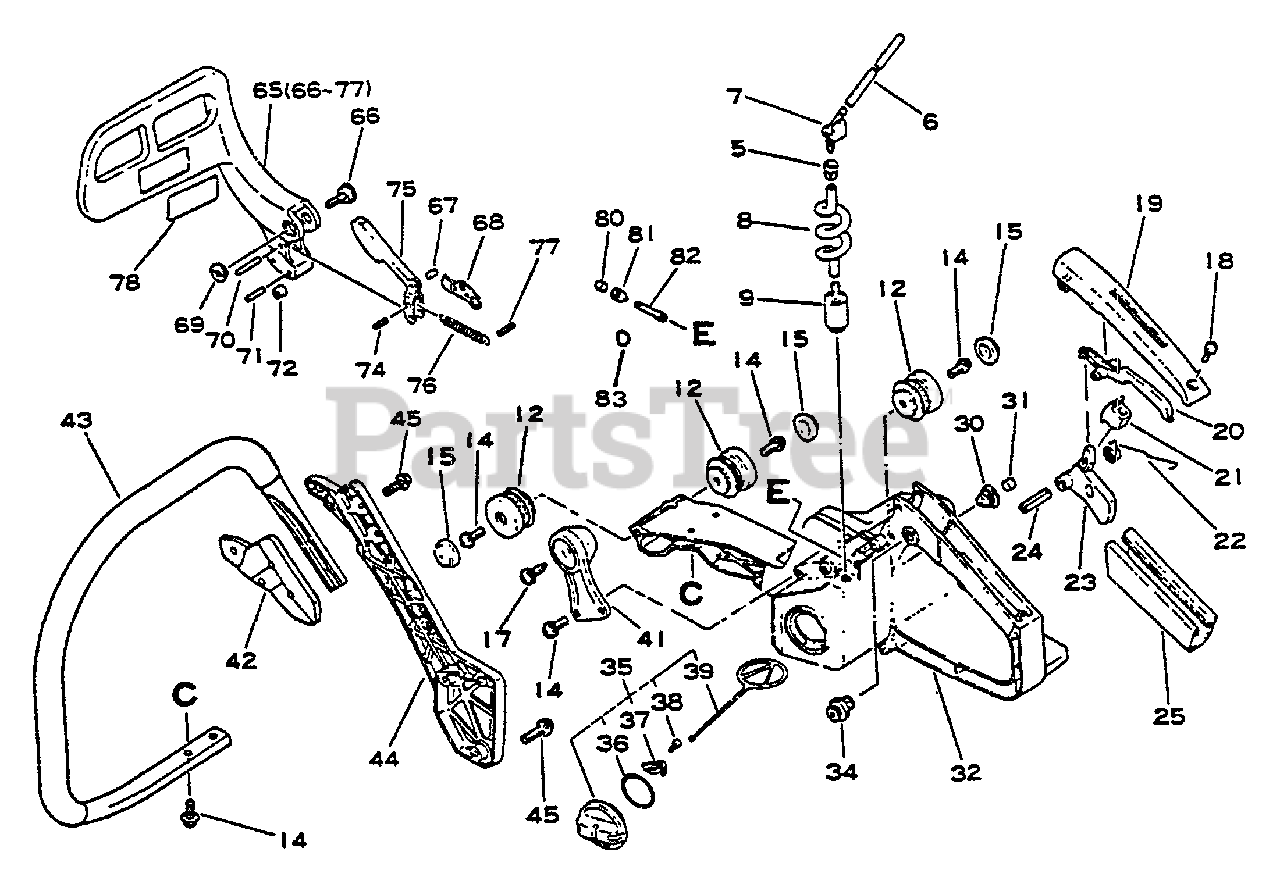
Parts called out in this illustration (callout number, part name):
5	GROMMET
6	PIPE, FUEL - 3×6×100
7	CONNECTOR, PIPE
8	PIPE, FUEL
9	FILTER, FUEL
14	SCREW 5×14
15	CAP, CUSHION
17	SCREW 5×14
18	BOLT 4×14
19	COVER, HANDLE
20	LEVER, THROTTLE LOCKOUT
21	CUSHION, THROTTLE
22	SPRING, THROTTLE RETURN
23	TRIGGER, THROTTLE - ORANGE
24	PIN, SPRING
25	GRIP, HANDLE
30	VENT ASSY
31	FILTER, CHECK VALVE
32	HANDLE - REAR
34	LOCK, THROTTLE TRIGGER
35	CAP ASSY
36	O-RING 29
37	RETAINER, CONNECTOR
38	SCREW 3×8
39	CONNECTOR, CAP L= 60 MM
42	BRACKET, HANDLE
43	HANDLE, FRONT
44	BRACKET, HANDLE
45	SCREW 5×20
65	LEVER ASSY, BRAKE
67	PIN, SPRING - 4×8
68	STOPPER
70	PIN 3×24
71	PIN 3×18
72	SPACER
74	PIN, SPRING 3×12
75	WEIGHT, BRAKE
76	SPRING, RETURN
77	PIN, SPRING
80	VENT ASSY
81	HOLDER, VENT
82	PIPE, VENT
